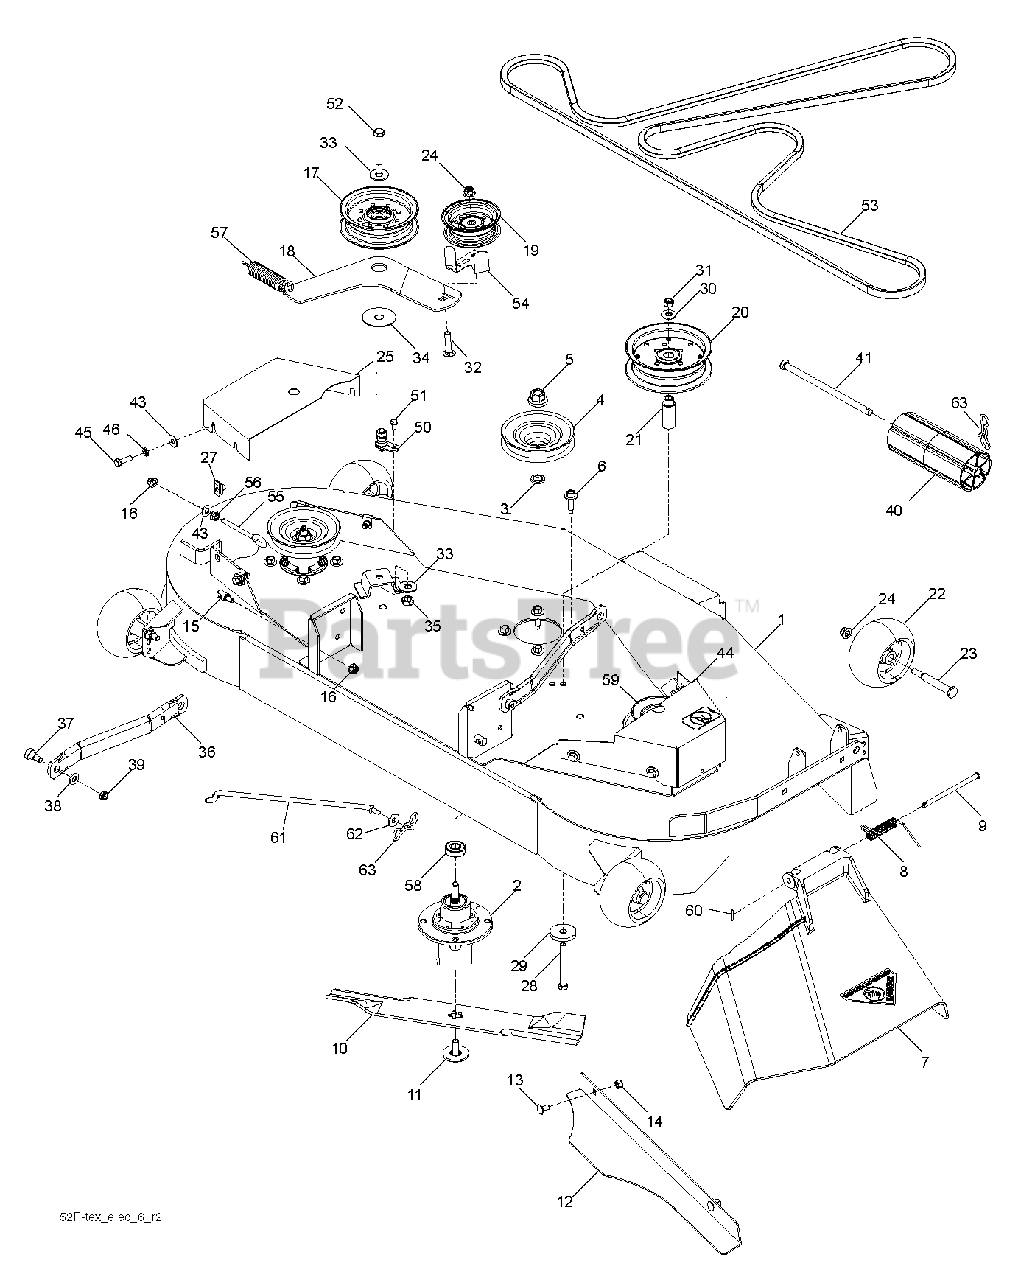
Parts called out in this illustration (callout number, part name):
1	DECK 52" FAB WELDMENT ORANGE
2	MANDREL.DECK.ASSEMBLY
3	WASHER.SPACER.MANDREL
4	PULLEY.DRIVEN.DECK.48'
5	NUT.FLANGE.LOCK.TOP
6	WASHER HEAD SCREW
7	DISCHARGE CHUTE 52"
8	SPRING - TORSION
9	PIN-CLEVIS 5/16 DIA X 5.19 ZD
10	BLADE, 17.75 X 2.5 X .25
11	BOLT.WASHER.ASM.7/16-2
12	PLATE.52".CONFINEMENT.BLACK
13	CARRIAGE BOLT 5/16C X 5/8"
14	NUT 5/16 NYLOC
15	STUD.FASTNER.W/ANTI-ROTATE
16	5/16-18 NYLOC FLANGE NUT
17	PULLEY.IDLER.MWR.STATI.LH
18	ARM IDLER 52"
19	PULLEY.IDLER.FLAT
20	PULLEY, IDLER
21	BUSHING, IDLER
22	WHEEL GAGE DONUT
23	BOLT.SHOULDER.3/8-16X3-5/8.
24	NUT 3/8-16 HEX FLG NYLOC ZD
25	SHIELD.BELT.LH.ORANGE
27	U-CLIP 5/16-18 NUT RETAINER
28	HCS 3/8-16 X 3-1/2 GR5 ZD
29	SPINDLE WASHER
30	RP WASHER 3/8 FLAT
31	NUT 3/8-16 NYLOC
32	RHSNB 3/8-16X1-3/4
33	WASHER 7/16 FLAT ZD
35	NUT.LOCK.FLANGE.7/16
36	ARM.SUSPENSION.MOWER
37	SB 3/8-16 X 3/8 SKT HD ZD
38	WASHER 3/8 SAE FLAT
39	NUT HEX 3/8-16 NYLON, THIN
40	NOSE ROLLER 48"
41	ROD.ROLLER.NOSE.NARROW.48"
43	WASHER 5/16 FLAT
44	SHIELD.BELT.RH.52.ORANGE
45	HCS 5/16C X 1
46	WASHER 5/16 LOCK
50	PORT.WASHOUT
51	BOLT 1/4-20 X 1/2 HWST
52	BOLT 7/16-14 X 2-1/2 GR 5 ZD
53	BELT, 143.5" EL
54	BELT GAURD
55	EYE BOLT 5/16 X 3.50
56	NUT 5/16C WHIZ
58	BEARING, BALL
59	RP PULLEY, COLLECTION 48
60	RETAINER CLIP
61	ROD.ANTI.SWAY.48/54"TE
62	WASHER
63	PIN.COTTER.5/16.BOW TI
